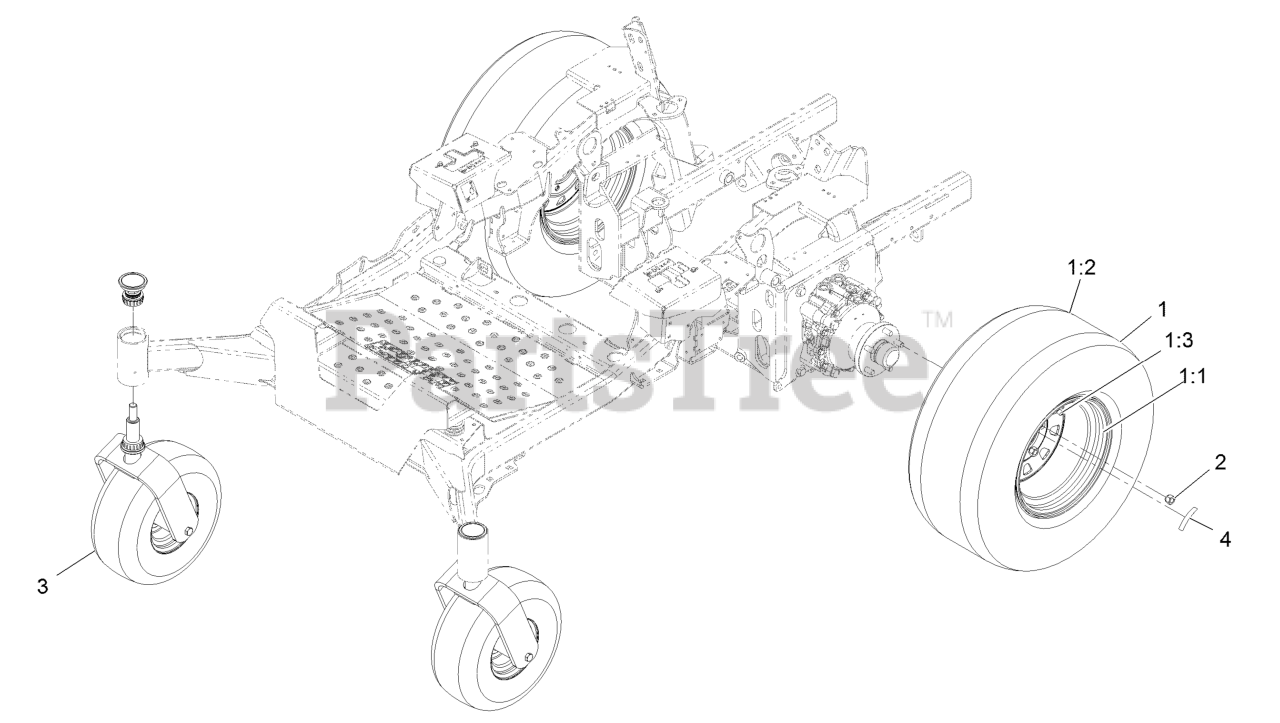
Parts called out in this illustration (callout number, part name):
1	ASM-Tire 26X12-12, 1.0 Offset
1:1	Rim ASM, 1.0 Offset
1:3	Stem-Valve
2	Nut-Lug 1/2-20
3	ASM, Wheel Caster
4	Decal-Torque, Wheel Nut
